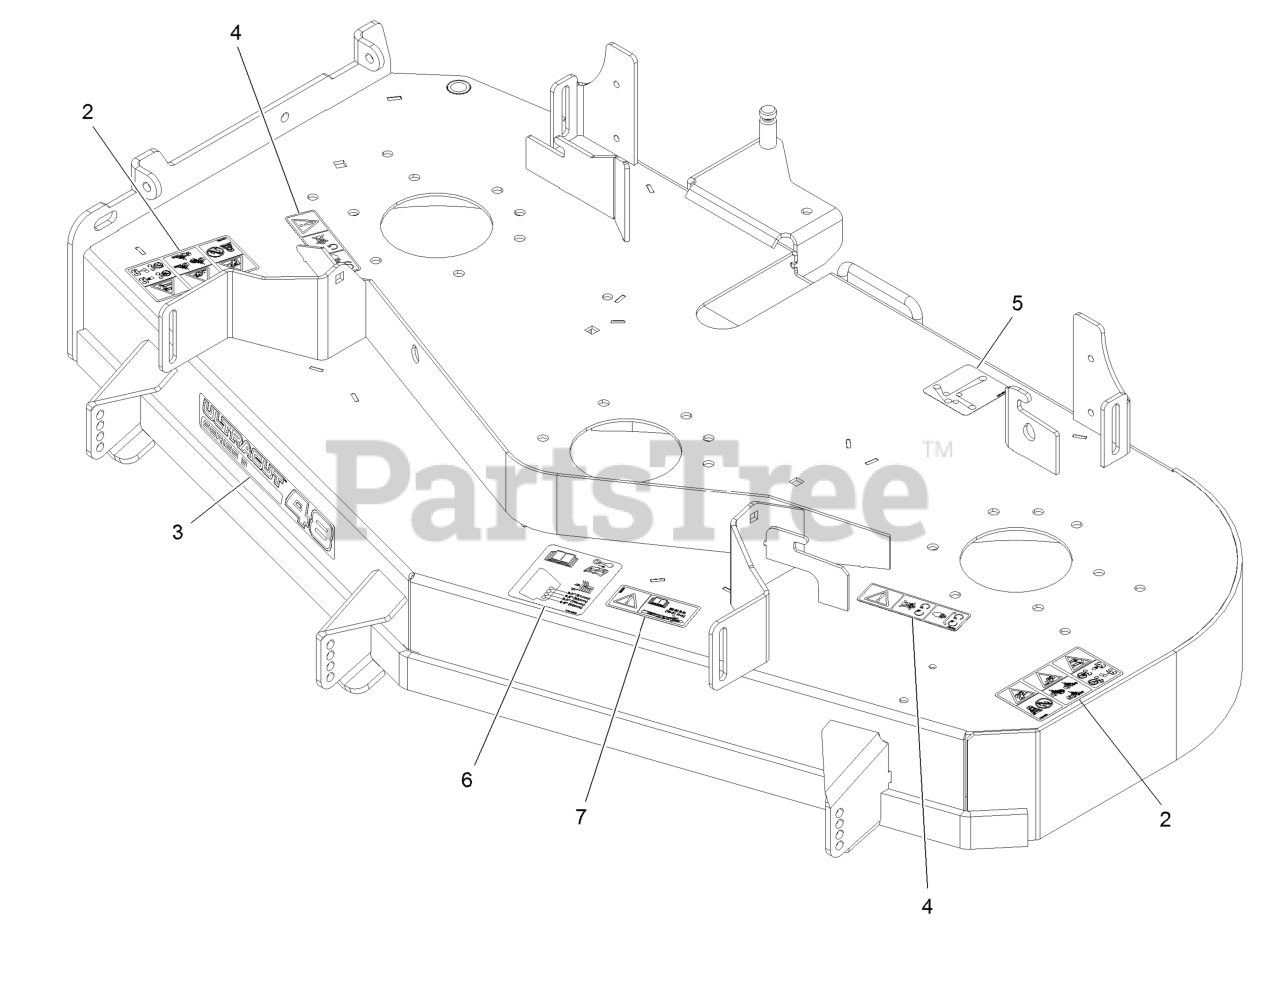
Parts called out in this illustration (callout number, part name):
2	Decal-Danger Thrown Objects
3	Decal-Ultracut 48 Series 3
4	Decal-Missing, Cover
5	Decal-Routing, Belt
6	Decal-Roller, Anti-Scalp
7	Decal-Bolt Torque
